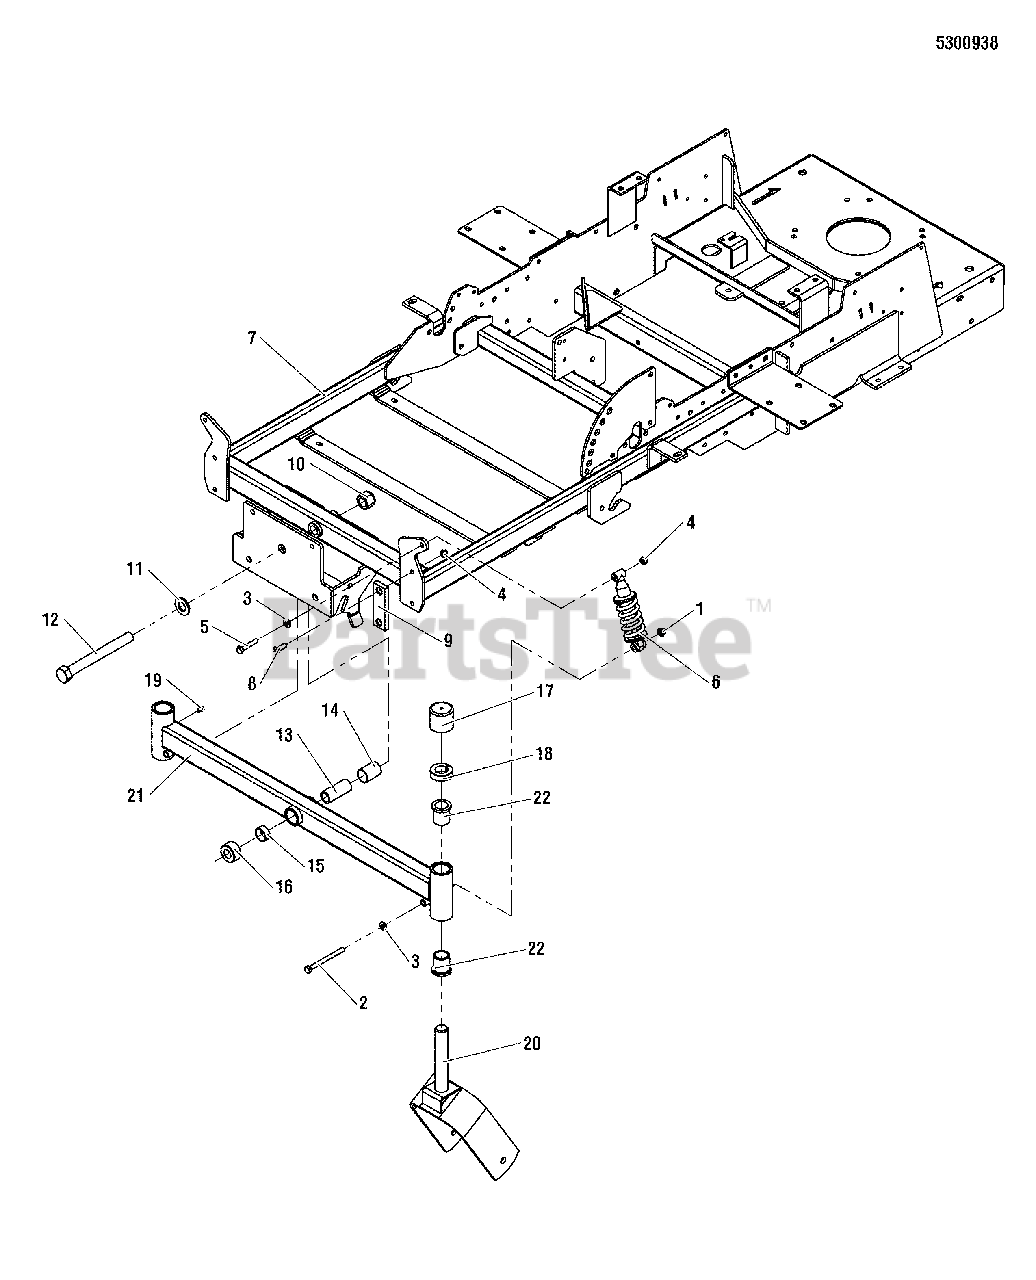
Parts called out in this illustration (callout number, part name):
1	NUT, 5/16-18 HEX NYLOCK FLANGE
2	BOLT, 5/16-18 X 3-3/4 GD5
3	WASHER, 5/16" SAE
4	NUT, 5/16-18 HEX NYLON LOCK
5	BOLT, 5/16-18 X 1-3/4 GD5 YZ
6	SHOCK
7	WELD, MAIN FRAME
8	SCREW, 5/16-18 X 1 FLAT HD SC
9	PAD, FRICTION, .375 X 1.25 X 4.00
10	NUT, 3/4-16 HEX NYLON LOCK
11	WASHER, 3/4" SAE
12	BOLT, 3/4-16 X 7" YZ GD5
13	SPACER, .75 X 1.00 X 2.38
14	PIVOT BEARING, 1.00" X 1.125" OD X 1.50"
15	PIVOT BEARING, 1.00 X 1.125 OD X .50
16	SPACER, .76X 1.50 X .79
17	CAP, VINYL 1.687 X 1-1/2
18	COLLAR, 1" SPLIT
19	GREASE FITTING, 1/4-28 STRAIGHT
20	WELD,CASTER YOKE
21	WELD, PIVOTING FRONT END - ORG
22	BUSHING, FLANGE
